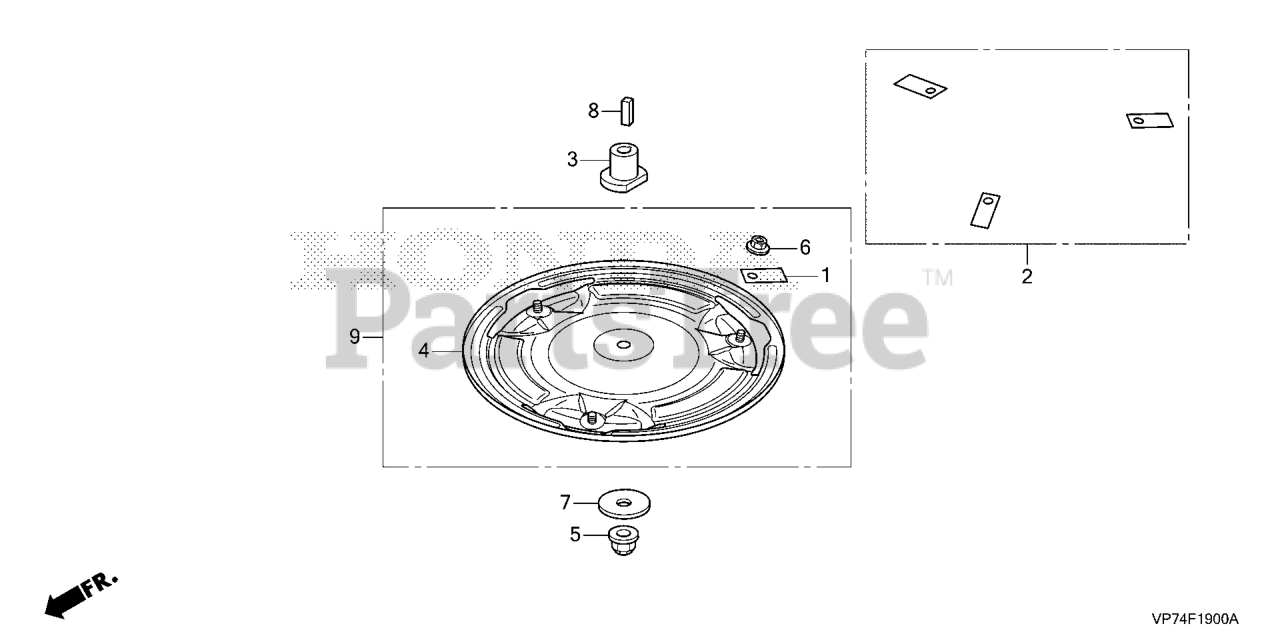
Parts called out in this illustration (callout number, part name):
1	BLADE, ROTARY
2	BLADE SET, ROTARY
3	HOLDER, BLADE DISK
4	DISK, BLADE
5	NUT, SELF-LOCK (8MM)
6	NUT, BLADE (5MM)
7	WASHER (8.5X32X1.5)
8	KEY FLAT (4X4X14)
9	DISK KIT, BLADE
